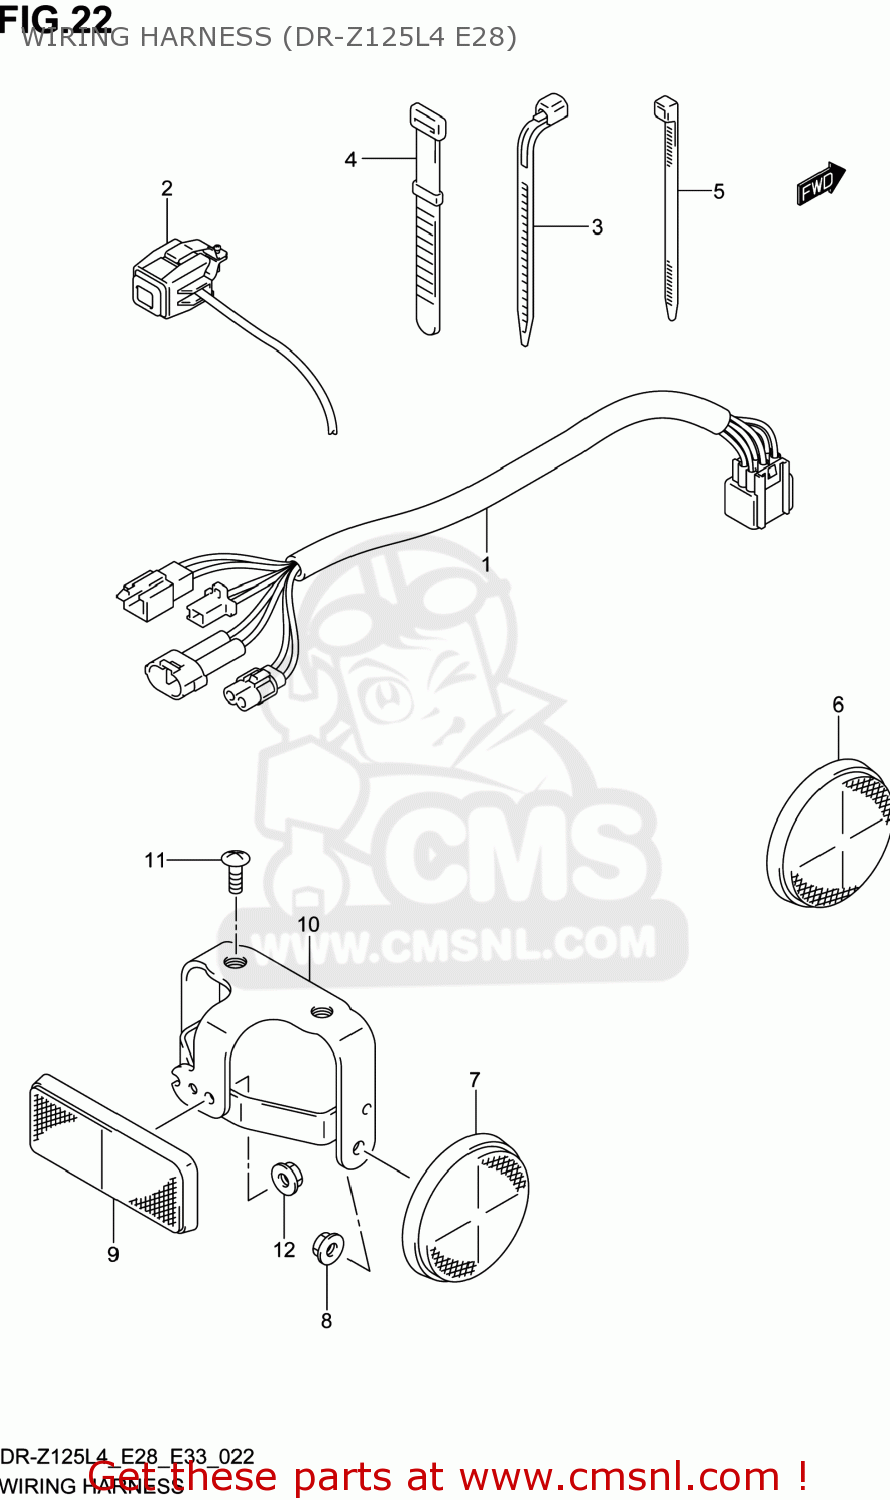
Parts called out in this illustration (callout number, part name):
1	HARNESS,WIRING
2	SWITCH ASSY,ENGINE STOP
3	CLAMP(L:165)
4	CLAMP(L:120)
5	CLAMP(L:145)
6	REFLEX REFLECTOR ASSY,FR SIDE
7	REFLEX REFLECTOR,RR
8	NUT
9	REFLECTOR ASSY,RR
10	BRACKET,SIDE & RR REFL
11	SCREW
12	NUT
